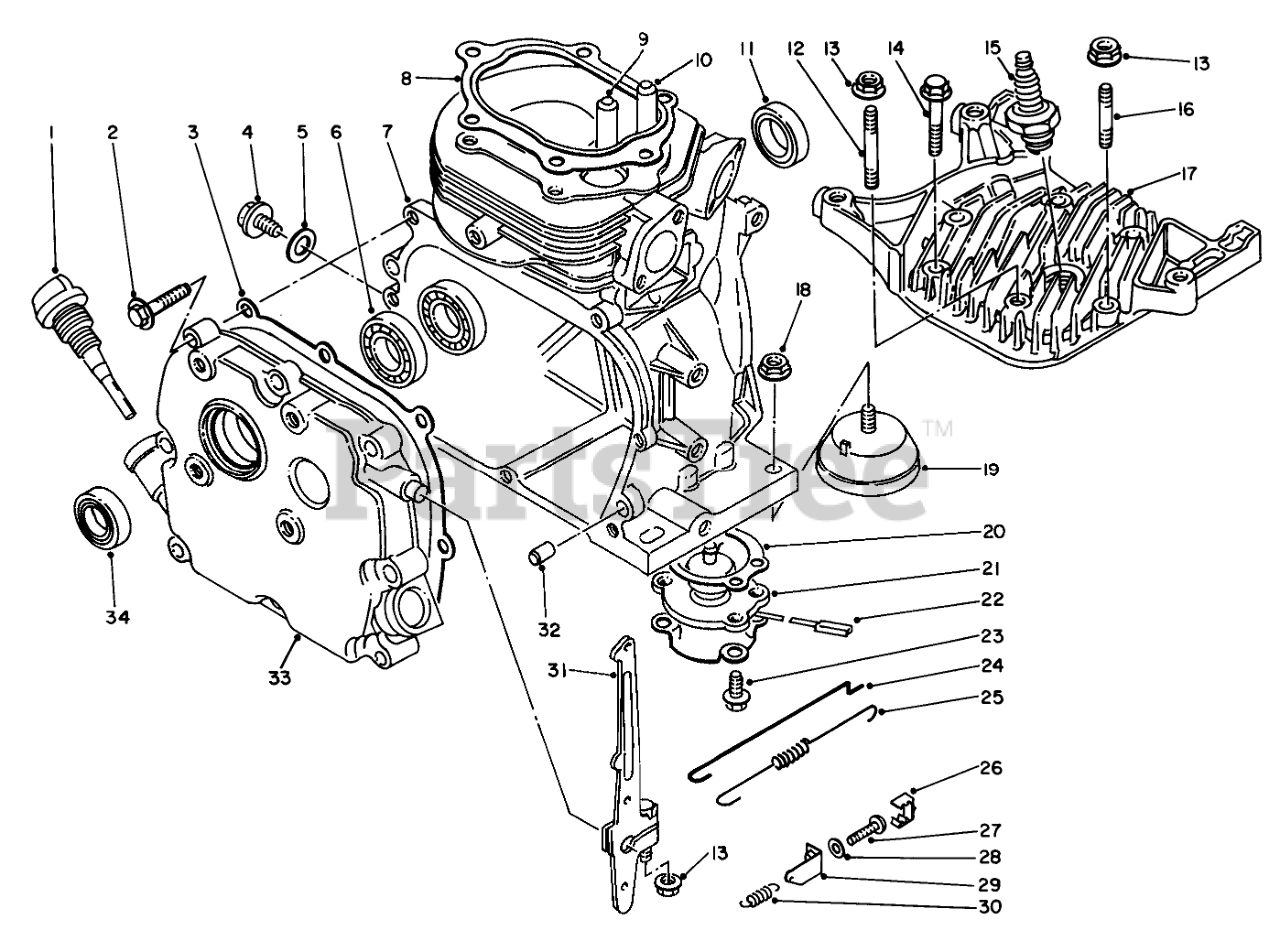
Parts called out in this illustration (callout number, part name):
1	Gauge-Oil Level
3	CRANKCASE GASKET
4	OIL DRAIN PLUG
5	Gasket
6	Bearing
7	Cylinder Assembly
8	CYL. GASKET
9	Guide-Exhaust Valve
10	Guide-Intake Valve
11	OIL SEAL
12	Bolt-Stud
15	SPARK PLUG
16	Bolt-Stud
17	Cylinder Head
19	MOUNTING
20	GASKET
21	SENSOR
22	Plate
24	Rod-Carburetor
25	SPRING
27	Screw
28	Washer
29	Hook-Governor
30	SPRING
31	Lever-Throttle Conlrol
33	Cover-Crankcase Side
34	OIL SEAL
